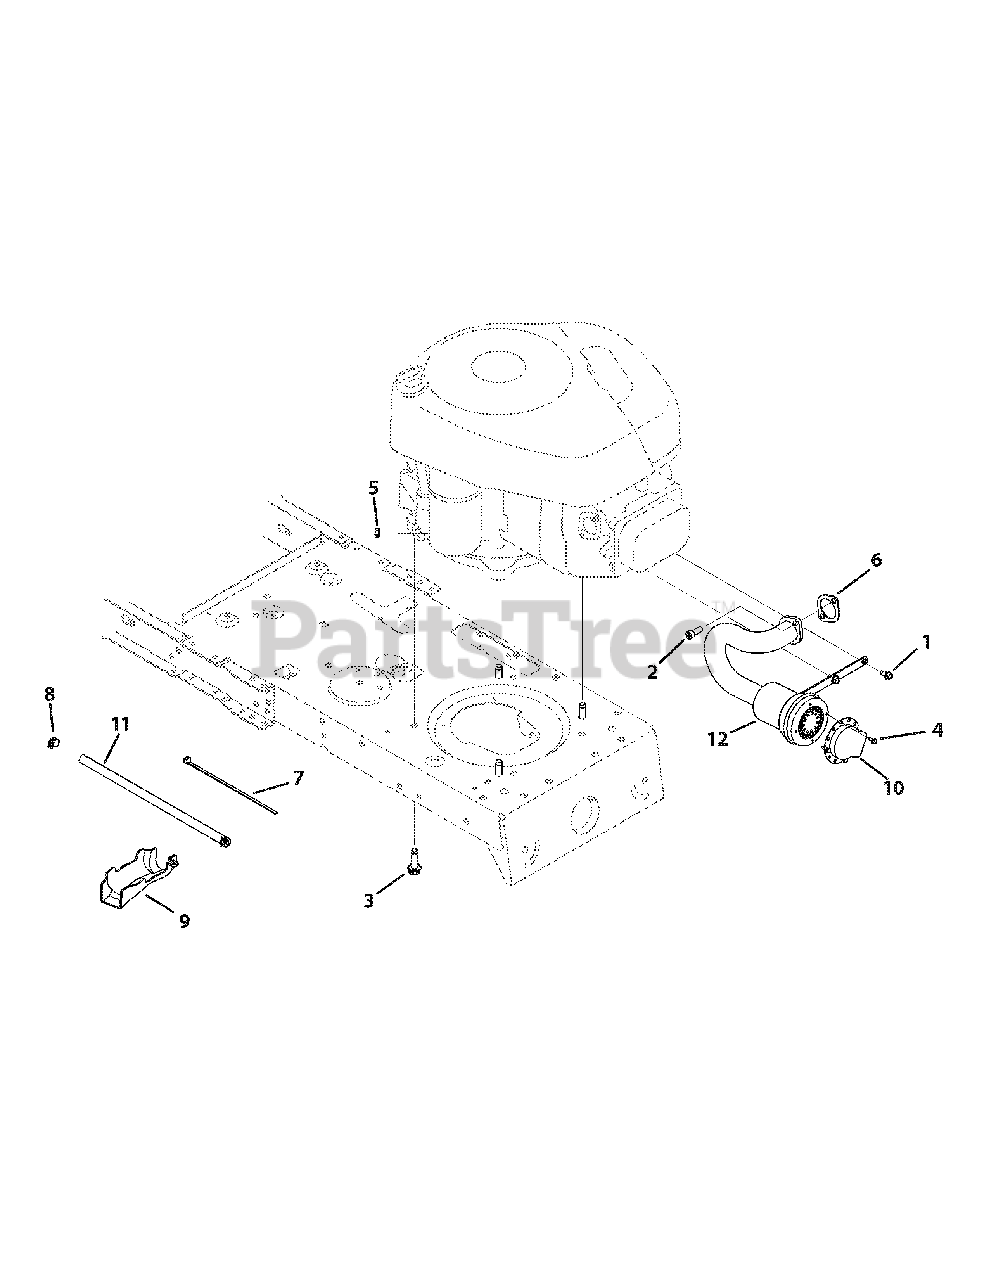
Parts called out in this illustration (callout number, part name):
1	Hex Wash S-Tapp Scr 1/4-20 x .50
2	Socket HD Cap Scr. 5/16-18 x .75
3	Hex Wash S-Tapp Scr 3/8-16 x 1.0
4	Hex Wash HD AB S-Tapp Scr #8-.50
5	Sems Nut 1/4-20
6	Exhaust Gasket
9	Oil Drain Sleeve
10	Muffler Deflector
12	Muffler
